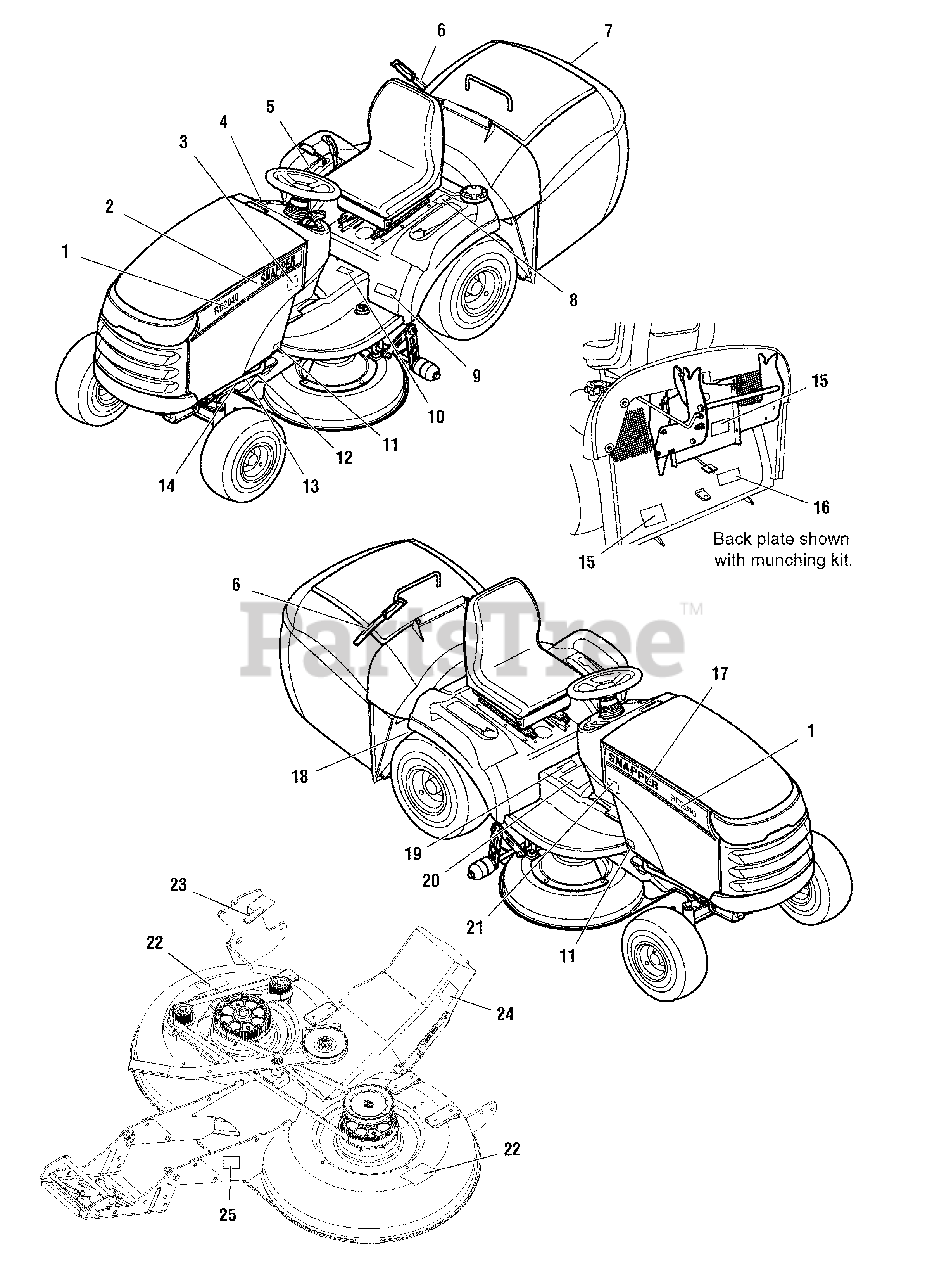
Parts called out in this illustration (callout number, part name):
1	DECAL, RD2140
1	DECAL, RD1840
2	DECAL, Hood Stripe, Snapper, LH
3	DECAL, Belt & Blade
4	DECAL, Ignition Switch
5	DECAL, Crusie / Lift
6	DECAL, Hopper Lever
7	DECAL, Snapper
8	DECAL, Latch Release
9	DECAL, Baron XL
10	DECAL, Hopper Pedal
11	DECAL, Protective, Clear
12	* DECAL, Patent
13	* DECAL, Serial Number, Tractor
14	* DECAL, Decible Power Mass, Export Only
15	DECAL, Danger Operating W/O Catcher
16	DECAL, Drawbar Max Load
17	DECAL, Hood Stripe, Snapper, RH
18	DECAL, Transmission Release Valve
19	DECAL, Danger Catcher Open
20	DECAL, Warning/Danger Icons, Tunnel
21	DECAL, Touch Up Paint
21	DECAL, Touch Up Paint, Orange, Black, Red
22	DECAL, Danger Rotating Blade, Export Only
23	DECAL, Height Of Cut
24	DECAL, Danger, Discharge Tube
25	* DECAL, Serial Number, Mower Deck
26	DECAL, Steering Wheel, Snapper
32	FLANGED BUSHING, 3/8 ID X .63 OD X .55 LG
